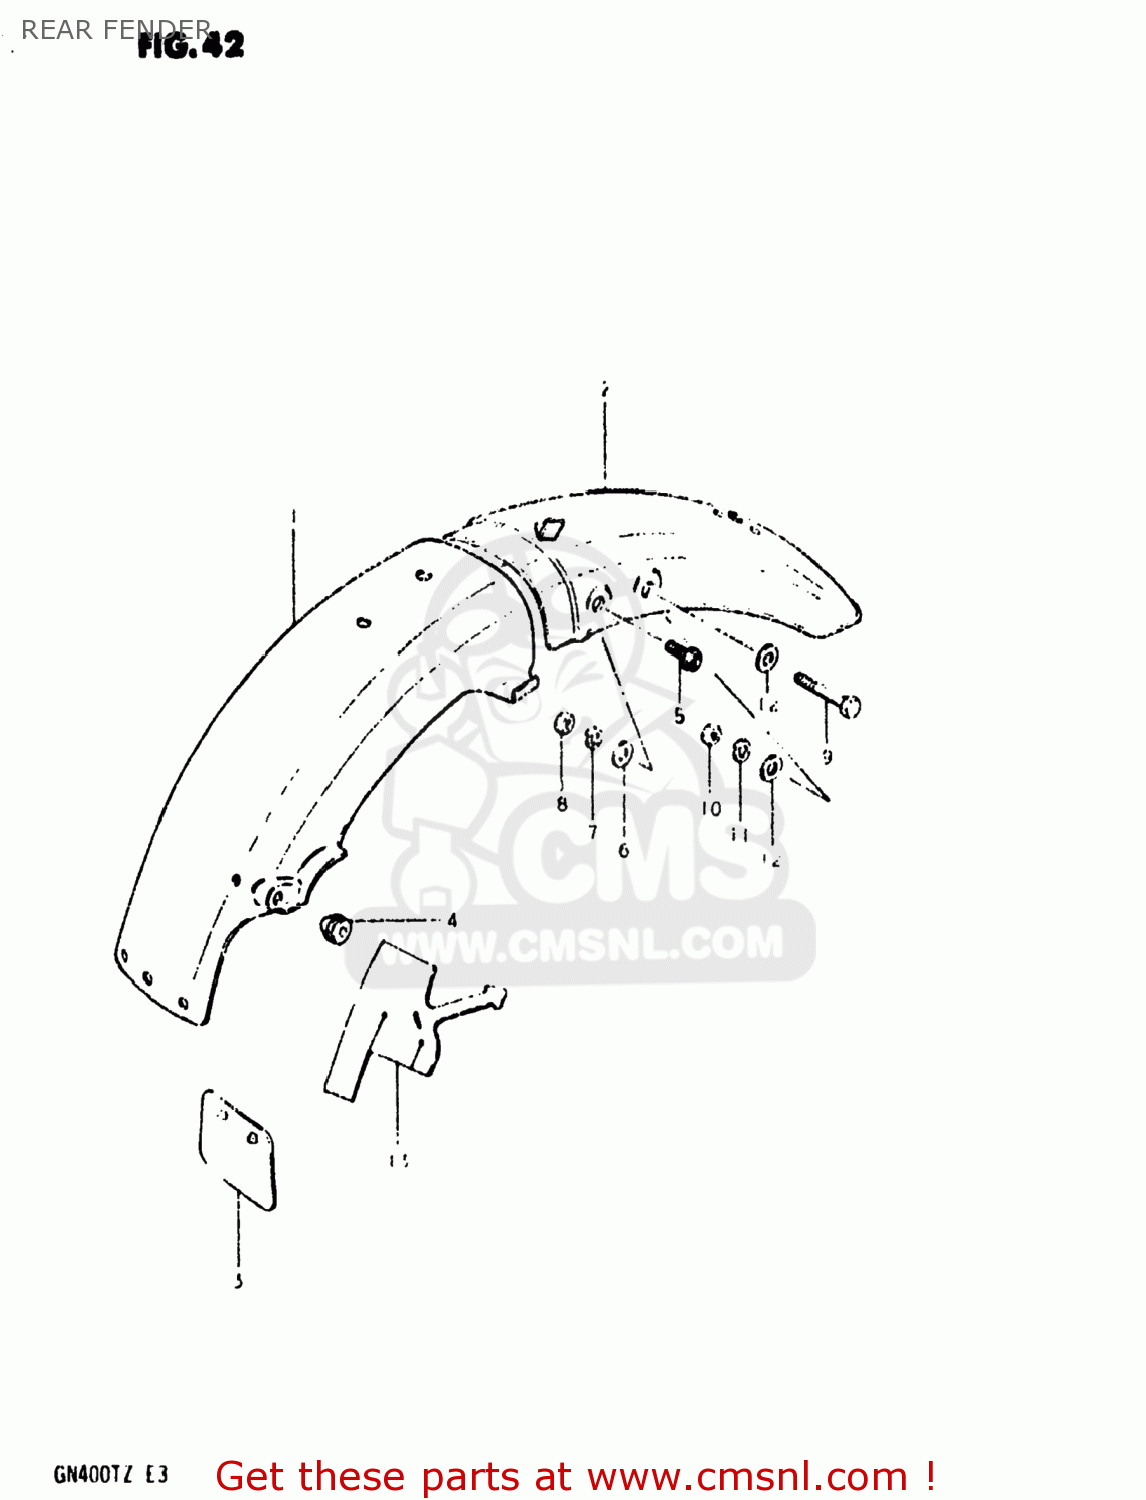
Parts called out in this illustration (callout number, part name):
1	FENDER,REAR
2	FENDER,REAR
3	MUD GUARD,REAR FENDER
4	CUSHION,REAR FENDER,FRONT
5	BOLT
6	WASHER
7	LOCK WASHER
8	NUT 8MM
9	BOLT
10	NUT 8MM
11	LOCK WASHER
12	WASHER
13	MUD GUARD,REAR FENDER
